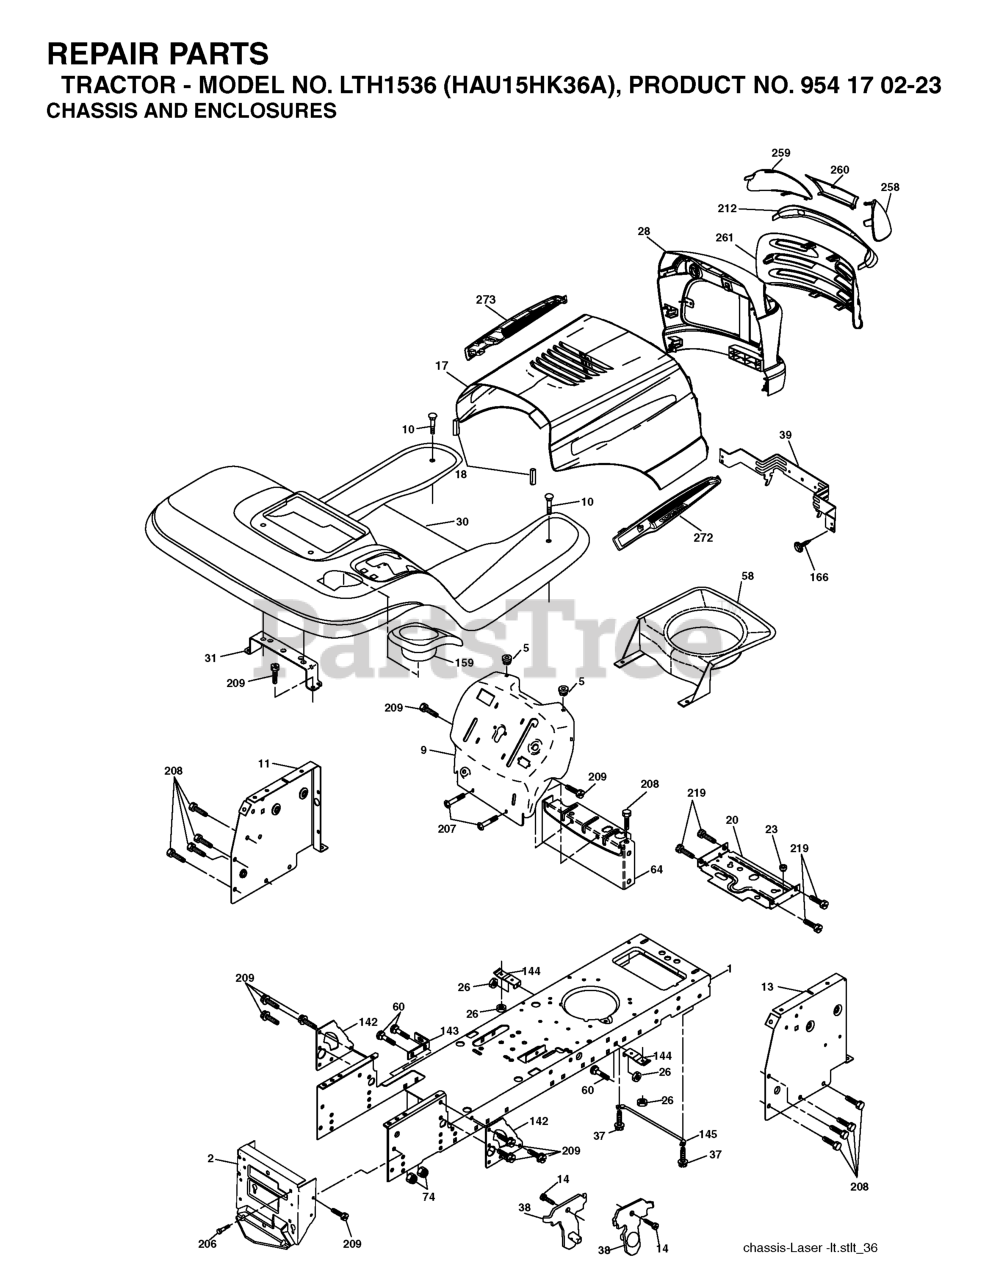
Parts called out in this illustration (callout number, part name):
1	CHASSIS STAMPING
2	DRAWBAR, 12GA
3	SCREW 3/8-16X3/4
5	BUMPER.RUBBER.HOOD
9	DASH
10	BOLT D
11	PANEL.DASH.LH.LTX
13	PANEL DASH RH
17	VENT.HOOD.LASER.III
18	BUMPER.HOOD.LARGE.1.75"
26	NUT
30	FENDER FOOTREST
31	BRACKET.SUPPORT.FENDER
37	Screw 5/16-18 x 1/2 Hex, Self Tapping 5/16-18 x 1/2
38	BRACKET.ASM.PIVOT.MOWER.REAR
39	BRACKET PIVOT LASER
60	Bolt - Rd. Hd. Sq. Neckiage 3/8 16 x 3/4
64	DASH LOWER
142	PLATE REINFORCEMENT
143	BRACKET, SWAYBAR CHASSIS
144	BRKT, FOOT REST
145	ROD PIVOT CHASSIS/HOOD
166	SCREW
206	SHOULDER BOLT 5/16-18TT
207	SCREW, 5/16-18 X 1/2
208	SCREW 3/8-16X1/2
209	SCREW, 3/8-16X3/4
212	INSERT.LENS.REFLECTIVE
258	LENS LH
259	LENS LH
260	COVER.LENS.HUSQ.LASER
272	VENT.HOOD.LASER.
273	VENT.HOOD.LASER.
